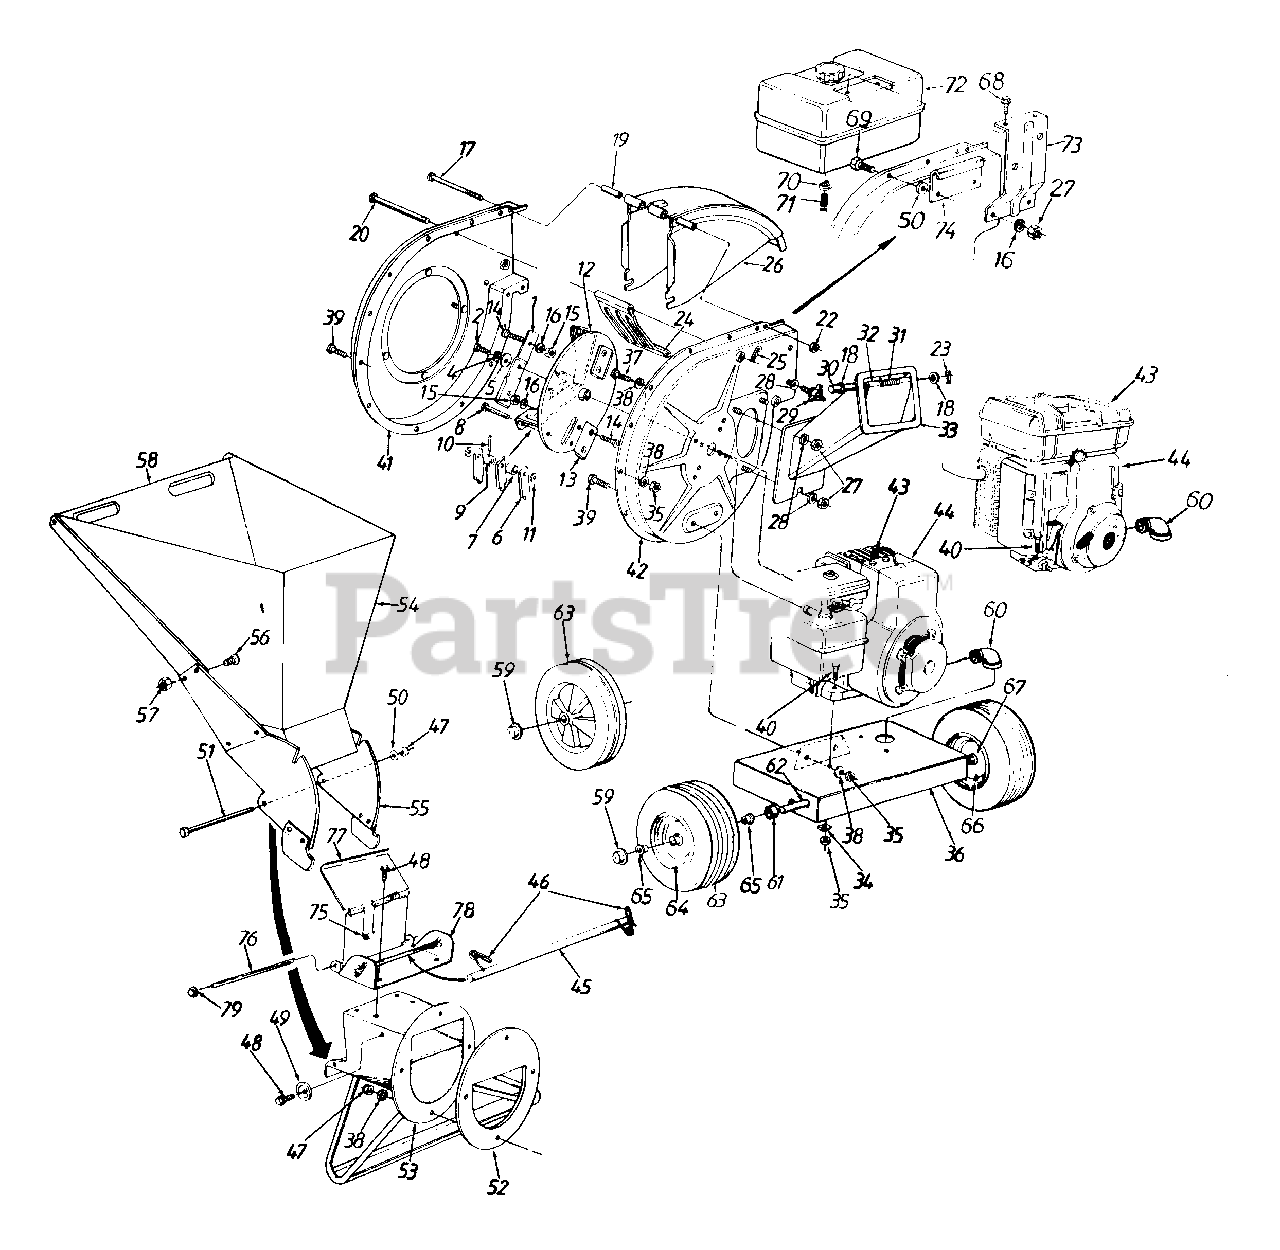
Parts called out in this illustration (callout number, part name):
1	Blade
2	Hex Patch Bolt 3/8-24 x 2.25" (Gr. 8)
4	L-Wash. 3/8" I.D. H.D.
5	Fl-Wash. .406" I.D. x 1.25" O.D. Hdn.
6	Flail
7	Flail Spacer
8	Clevis Pin .496" Dia.
9	Flail Spacer w/.160" Dia. Hole
10	Spring Roll Pin 1.125" Lg.
11	Fl-Wash. .531" I.D. x .94" O.D.
12	Impeller Ass'y. Comp.
13	Chipper Blade
14	Flat Hd. Scr. 5/16-24 x .75" Lg.
15	Hex Top L-Nut 5/16-24 (Gr. 5)
16	L-Wash. 5/16" I.D.
17	Hex Bolt 1/4-20 x 3.75" Lg.
18	Fl-Wash. .281" I.D. x .5" O.D.
19	Chute Hinge Spacer 1.66" Lg.
20	Clevis Pin .5" Dia. x 4.62" Lg.
22	Hex Ctr. L-Nut 1/4-20 Thd.
23	Cotter Pin
24	Shredder Screen
25	Internal Cotter Pin 3/8" Dia.
27	Hex Nut 5/16-18 Thd. (Gr. 5)
28	Bell-Wash. .345" I.D. x .88"
29	Hand Knob
30	Chipper Door Rod
31	Torsion Spring 1.14" Lg.
35	Hex Nut 5/16-18 Thd. (Gr. 5)
38	L-Wash. 5/16" I.D.
39	Hex Bolt 5/16-18 x .75" Lg. (Gr. 5)
40	Hex Bolt 5/16-18 x 1.75" Lg.
44	Engine
45	Release Bar
46	Torsion Spring 1.06" Lg.
47	Elastic Lock Nut 5/16-18 Thd.
48	Hex Wash. Hd. Self-Tap Scr. 5/16-18 x .75" Lg.
49	Stop Washer
50	Fl-Wash. 5/16" I.D.
51	Hex Bolt 5/16-18 x 8.38" Lg.
57	Hex L-Nut 1/4-20 Thd.
60	Drain Elbow (651C)
61	Spacer .64" I.D. x .38" Lg.
62	Shredder Axle
63	Wheel Ass'y. Comp.
66	Air Valve
67	Grease Fitting
68	Hex Hi-Low Scr. 1/4" x .75" Lg. (651C)
69	Hex Bolt 5/16-18 x .88" Lg. (651C)
70	Hose Clamp (651C)
71	Fuel Line - 7" Lg. (651C)
72	Fuel Tank Ass'y. Comp. (651C)
75	Torsion Spring
76	Hopper Door Rod
